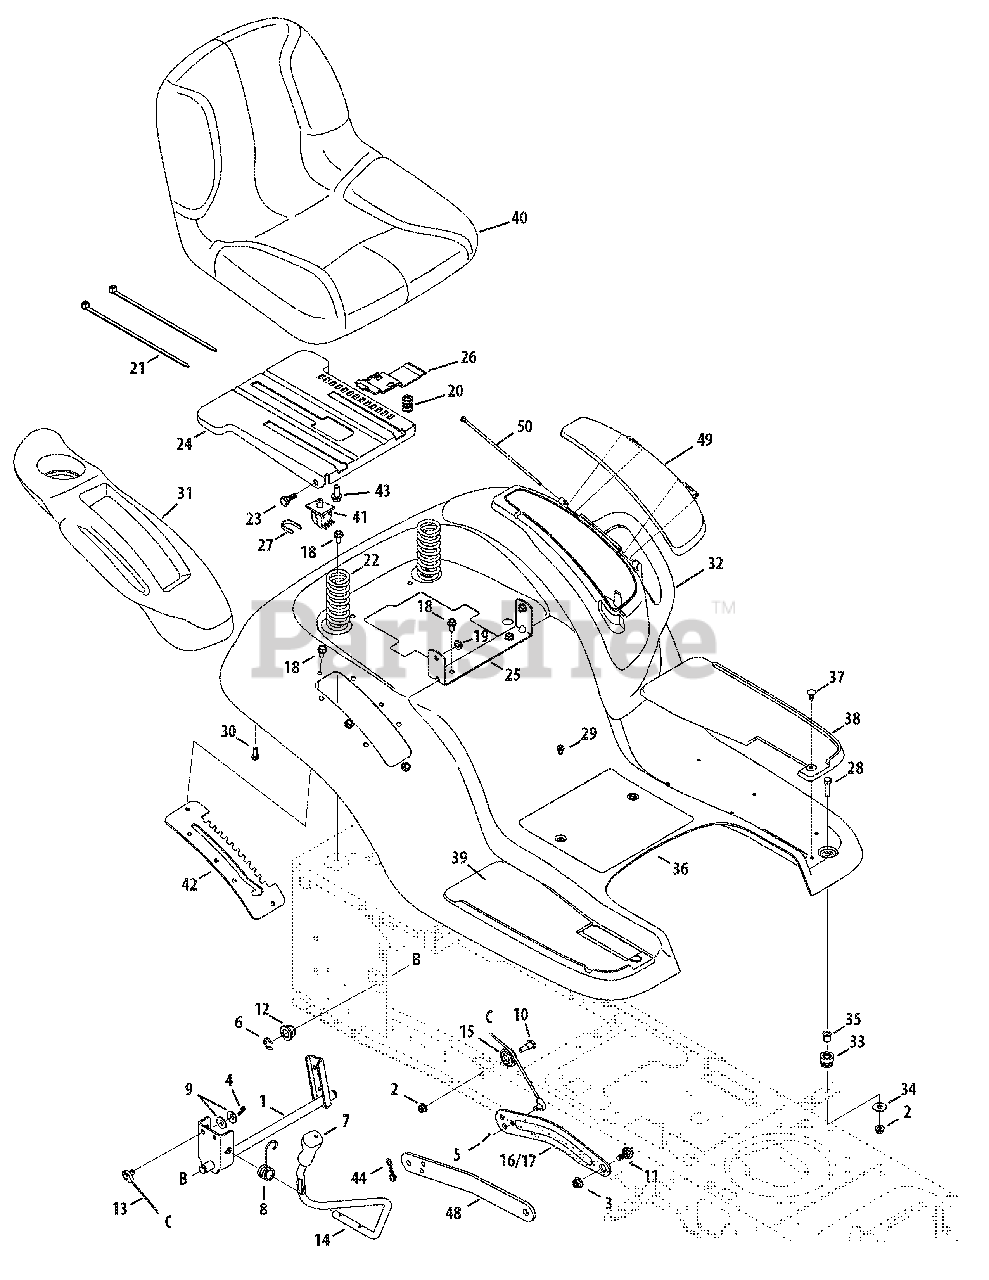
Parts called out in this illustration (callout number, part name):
1	Shaft Asm, Lift
2	Nut, Flange Lock, 5/16-18, Grf
3	Nut, Flange Lock, 3/8-16, Grf
4	Pin, Cotter, .072 Dia. x 1.13
5	Pin, Cotter, Bow-Tie 72 (42")
6	Ring, E Type, .625 Dia. Shaft
7	Grip, Handle, Cub, .50 ID
8	Spring, Torsion
9	Washer, Spring, .401 x .870 x .063
10	Screw, Shoulder, .437 x .470, 5/16-18
11	Bolt, Shoulder, .625, 3/8-16 (42")
11	Bolt, Shoulder, .50, 3/8-16 (46")
12	Bearing, Hex Flange
13	Cable, Lift, 16.16
14	Handle, Lift
15	Pulley, Roller, Cable
16	Arm, Lift, RH (42")
17	Arm, Lift, LH (42")
18	Screw, Self-tapping, 5/16-18, .750,
19	Nut, Flange Lock, 5/16-18, Gr5, Sd Lk
20	Spring, Comp, .68 x 1.065 x .055
21	Cable, Tie, 3/16 x .05 x 7.4
22	Spring, Comprs, 1.71 x 3.735 x .238
23	Screw, Shoulder, .437 x .268, 5/16-18
24	Bracket, Mounting, Seat
25	Bracket, Pivot, Seat
26	Lever, Seat Adjustment
27	Clip, Retaining, Switch
28	Hex Screw, 5/16-18, 1.25, Gr5, Std
29	Screw, Self-tapping, 1/4-20, 0.500
30	Screw, HL, 1/4-15, 0.750
31	Cover, Fender, RH
32	Cover, Fender, LH
33	Grommet, .4375 ID x .750
34	Washer, Flat .344 x 1.00 x .063
35	Spacer, Flange, .3125 x .4375 x .625
36	Fender, Cub Hydro
37	Clip, Ratchet, .250 Dia
38	Pad, Foot, LH
39	Pad, Foot, RH
40	Seat, High Back Cloth, Cub
41	Switch, Seat
42	Bracket, Lift, Manual PTO, 12 Pos
43	Hex Flange Bolt, 3/8/16, .875, Gr5
44	Pin, Cotter, Bow-Tie 72 (46")
48	Link, Lift (46")
49	Door, Cover, Fender
